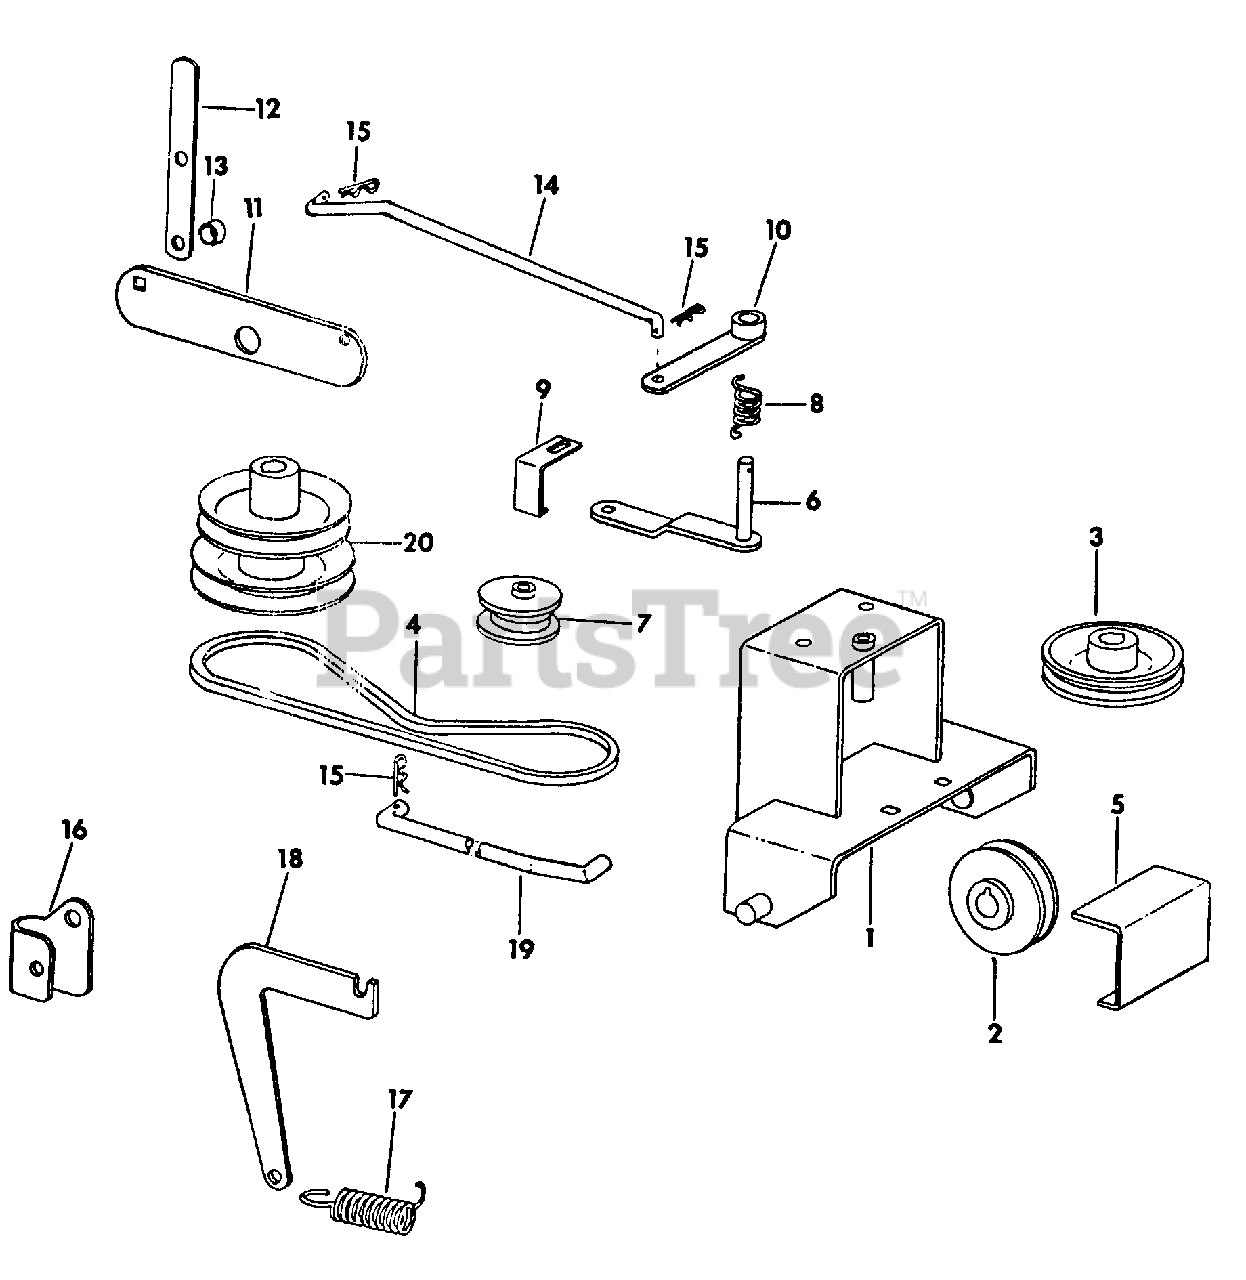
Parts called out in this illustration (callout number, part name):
1	Bracket, Gear Box
2	Sheave w/Set Screw
3	Sheave w/Set Screw
4	Belt, Drive
5	Shield, Sheave
6	Arm, Idler
7	Pulley, Idler
8	Spring, Torsion
9	Guide, Belt
10	Arm, Clutch
11	Plate, Mounting
12	Lever, Control
13	Spacer, Control Lever
14	Rod, Control
15	Pin, Control Rod Hair
16	Bracket, Lift Arm
17	Spring, Helper
18	Bracket, Helper Spring
20	Pulley, Drive
